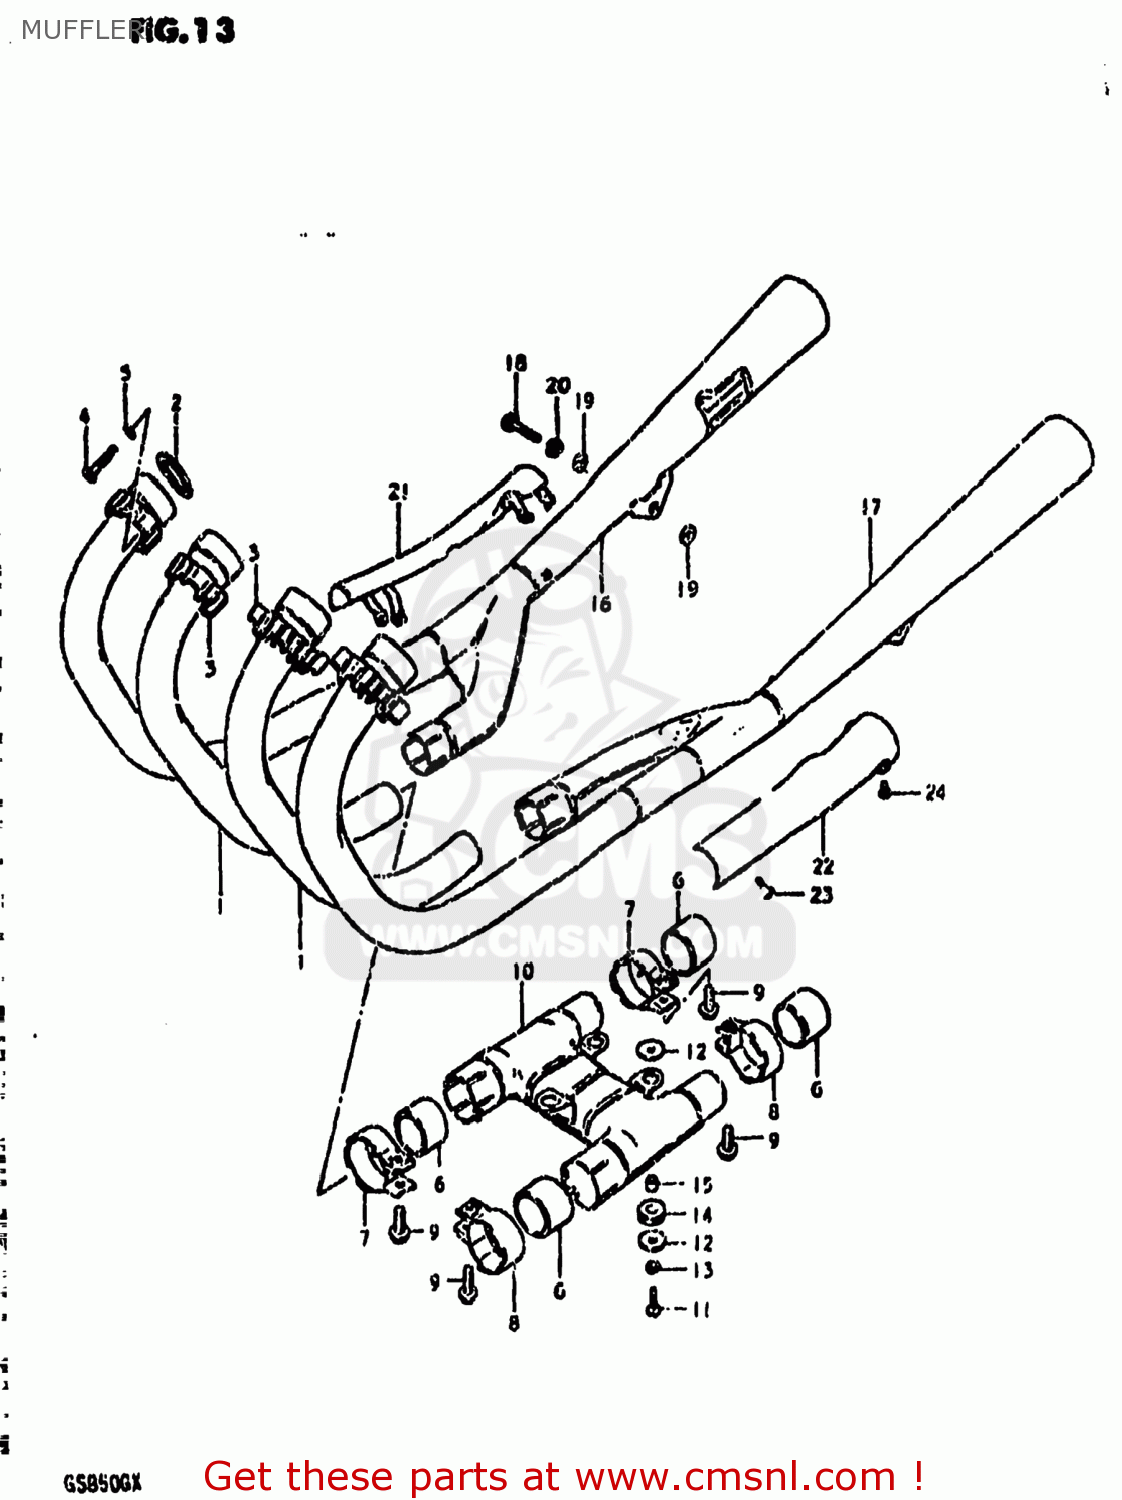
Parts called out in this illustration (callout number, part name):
1	PIPE,CENTER EXHAUST
2	GASKET,EXHAUST PIPE (NAS)
3	CLAMP,EXHAUST PIPE
4	BOLT
5	LOCK WASHER
6	CONNECTOR,MUFFLER
7	CLAMP,MUFFLER CONNECTOR,R
8	CLAMP,MUFFLER CONNECTOR,L
9	BOLT
10	BODY,PREMUFFLER
11	BOLT
12	WASHER
13	LOCK WASHER
14	CUSHION
15	SPACER(6.5X10.5X6.5)
16	BODY,MUFFLER
17	BODY,MUFFLER
18	BOLT 10X30
19	WASHER
20	LOCK WASHER
21	COVER,MUFFLER
22	COVER,MUFFLER
23	SCREW
24	SCREW
